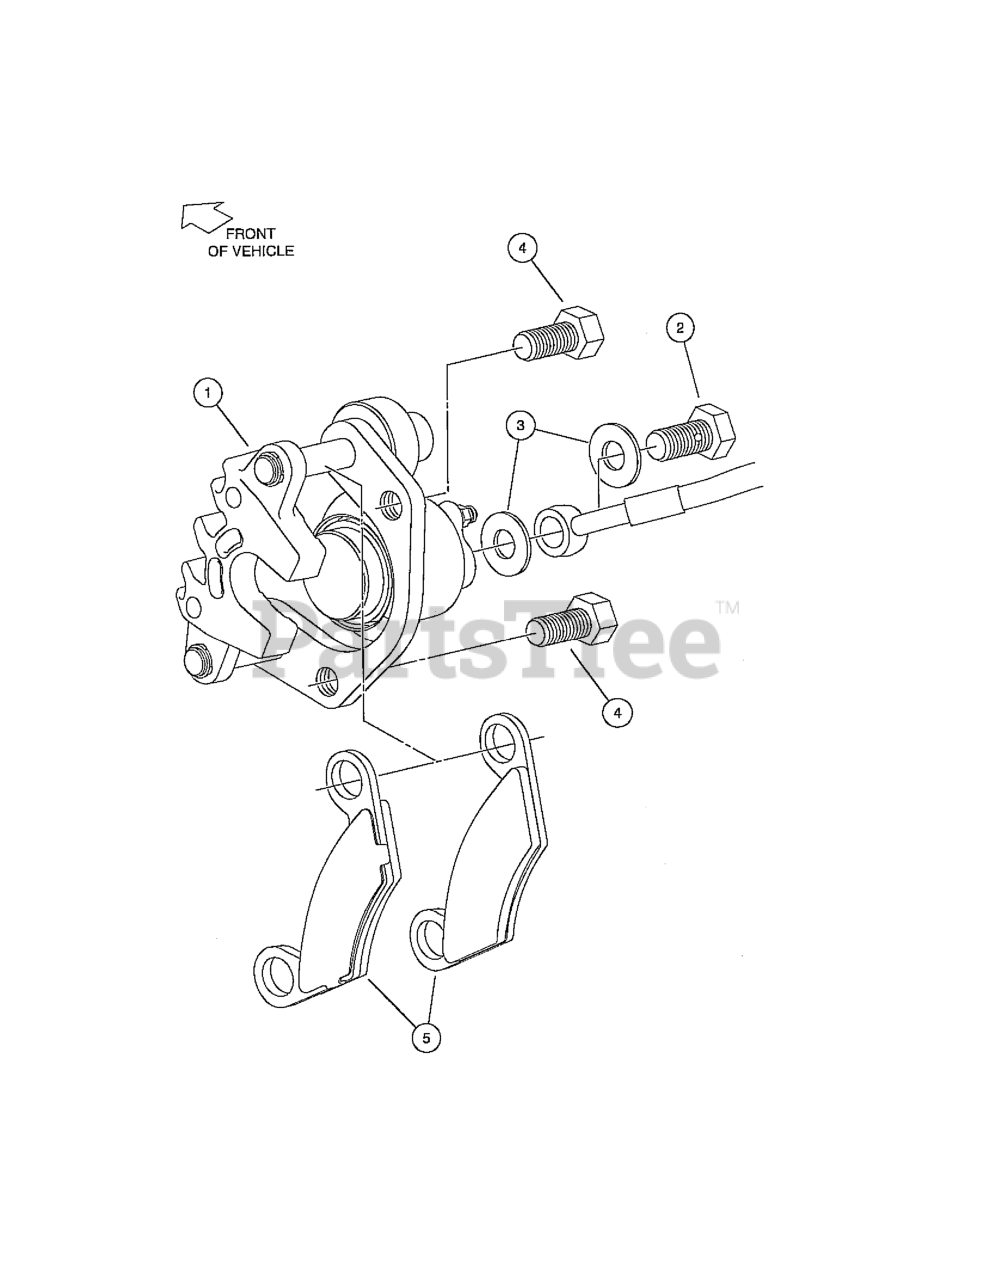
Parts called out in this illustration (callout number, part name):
1	BRAKE CALIPER, FRONT
2	BOLT, BANJO, M10X1X19
3	WASHER COPPER, M10 CRUSH
4	BOLT FLG, 3/8-24X.750 LOCTITE
5	SERVICE KIT, BRAKE PAD
